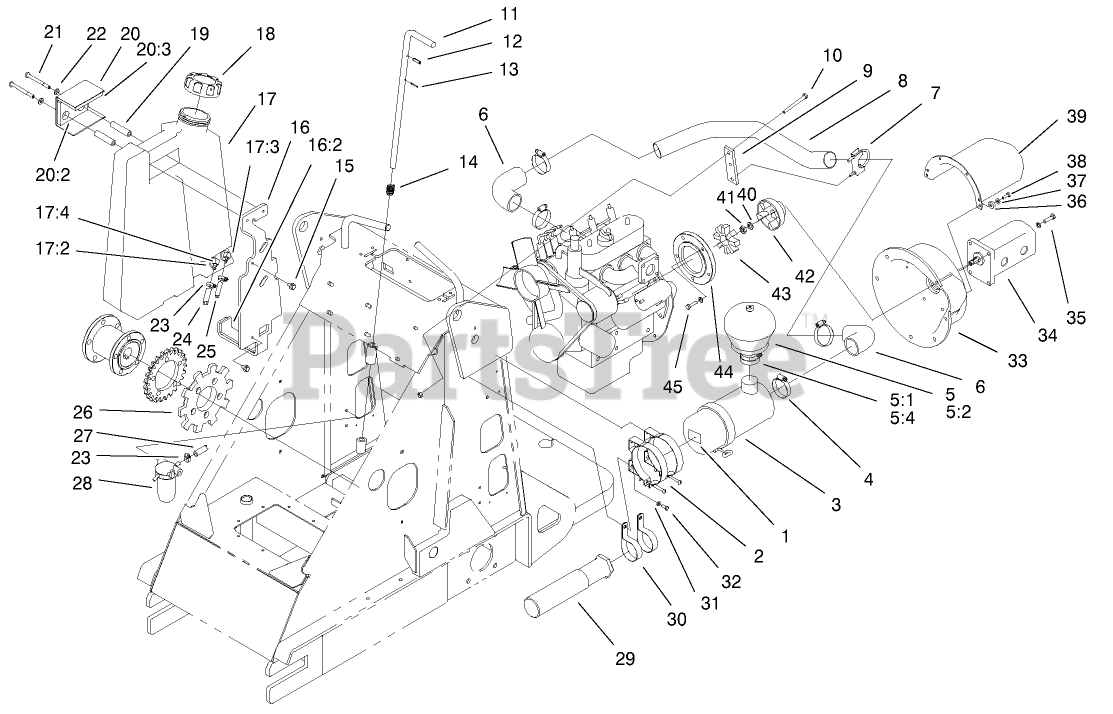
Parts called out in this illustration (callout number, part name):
1	DECAL-FLUID, STARTING
2	MTG BAND ASM
3	AIR CLEANER ASM
4	CLAMP-HOSE
5	PRE CLEANER
5:1	COVER ASM
5:2	BOWL-CLEAR
5:4	CLAMP
6	HOSE-AIR FILTER
7	U-BOLT
8	TUBE-AIR FILTER
8:1	SEAL KIT
9	MOUNT-TUBE
10	SCREW-HH
11	ROD-PARKING BRAKE
12	PIN-SPRING
13	PIN-ROLL, SLOT
14	SPRING-BRAKE
15	SCREW-FLANGE
16	MOUNT ASM
16:2	PAD-FOAM
17	FUEL TANK ASM, DIESEL
17:2	BUSHING
17:3	FITTING-90 DEG
17:4	FITTING-90 DEGREE
18	DIESEL FUEL CAP ASM
19	SPACER
20	PLATE ASM
20:2	PAD-FOAM
20:3	PAD-FOAM
21	SCREW-HH
22	WASHER-PLAIN
23	CLAMP-WORM
24	HOSE-FUEL
25	HOSE-FUEL
26	SPROCKET-BRAKE
27	HOSE
28	FUEL FILTER ASM
29	TUBE-MANUAL
30	CLAMP-R
31	WASHER-LOCK
32	SCREW-HH
33	MOUNT-PUMP, DIESEL
34	PUMP-GEAR, TANDEM
35	SCREW-CAP, HH
36	WASHER-RUBBER
37	WASHER-FLAT
38	SCREW
39	Guard-Pump
40	WASHER-LOCK
41	NUT-JAM
42	COUPLING
43	HUB-PUMP
44	COUPLER-PUMP, DIESEL
